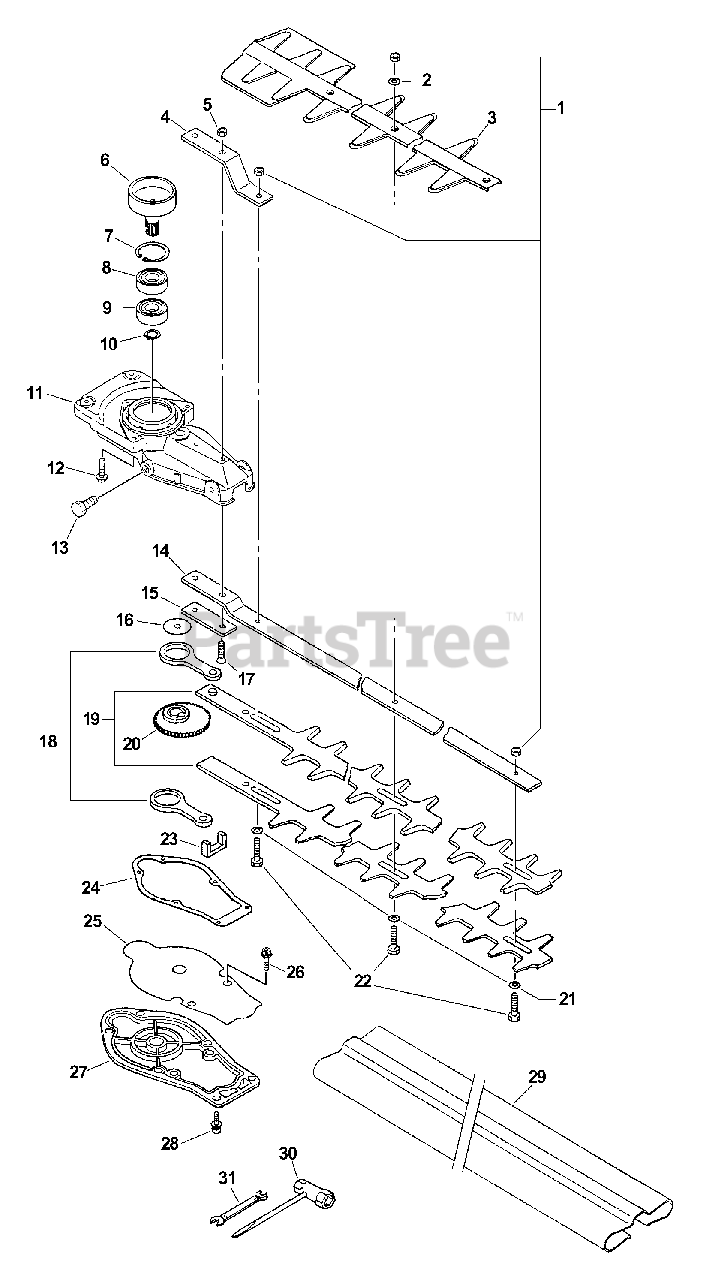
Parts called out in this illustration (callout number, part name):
2	WASHER 6.5×15.5×0.6
3	GUARD, CUTTER BLADE
4	PLATE, ANGLE
5	NUT, HEX M6
6	DRUM, CLUTCH
7	RING, SNAP 35
8	BEARING, BALL 6202
9	BEARING, BALL 6202
10	RING, SNAP 14
11	CASE, GEAR
12	BOLT 5×25
13	BOLT 8×8 SP
14	SUPPORT, BLADE
15	PLATE, EYE
17	SCREW 6×25
18	ROD, CONNECTING
19	BLADE, TRIMMER
21	WASHER 6.5×15.5×0.6
22	BOLT 6×20
24	GASKET, GEAR CASE
25	PLATE, GEAR CASE
26	BOLT 5×12
27	COVER, GEAR CASE
28	BOLT 4×12
29	COVER, BLADE
30	T-WRENCH 13×19×180
31	SPANNER 8×10
